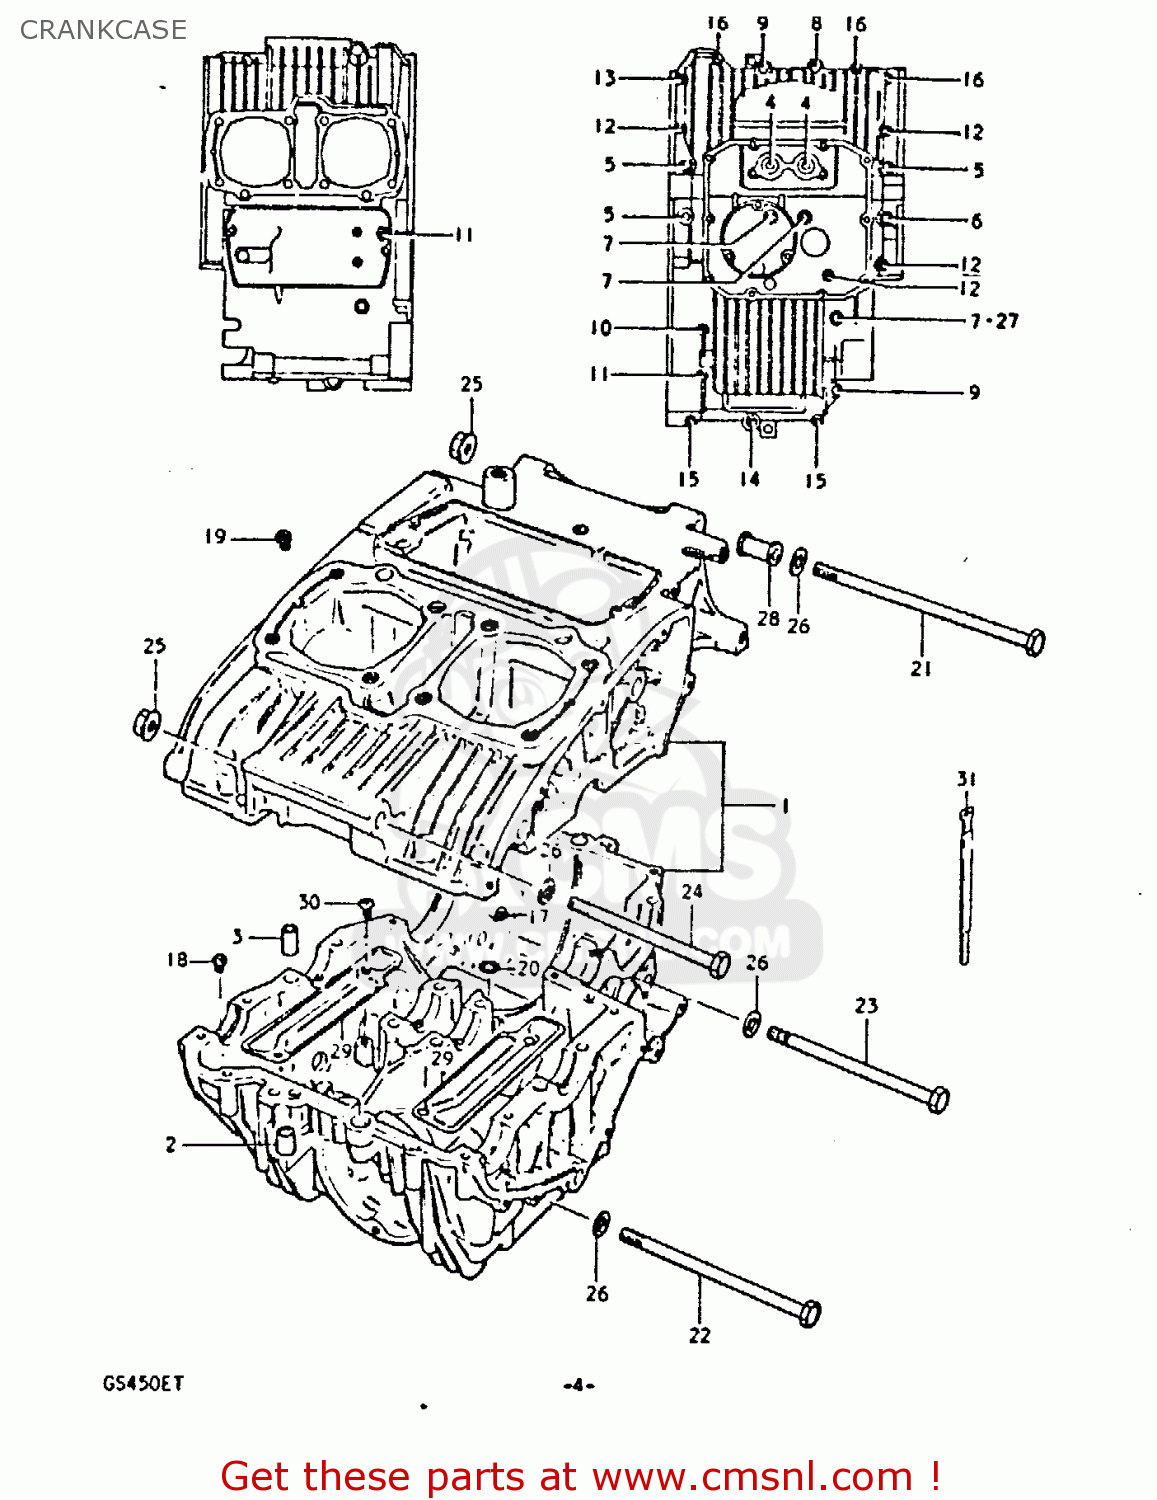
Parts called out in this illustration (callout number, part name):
1	CRANKCASE SET
2	PIN(10.4X13X22)
3	PIN (11X20)(SUS)
4	BOLT
5	BOLT
6	BOLT
7	BOLT
8	BOLT 8X65
9	BOLT (8X45)
10	BOLT
11	BOLT
12	BOLT (6X90)
13	BOLT (6X70)
14	BOLT 6X65
15	BOLT ,6X50
16	BOLT,UNDER
17	JET
18	JET
19	JET
20	O-RING
21	BOLT 10X250
22	BOLT
23	BOLT 10X160
24	BOLT
25	NUT 10MM
26	WASHER
27	GASKET 8.2X14X1 (NAS)
28	SPACER,ENGINE MOUNT
29	PLATE,OIL SEPARATOR
30	SCREW
31	CLAMP
